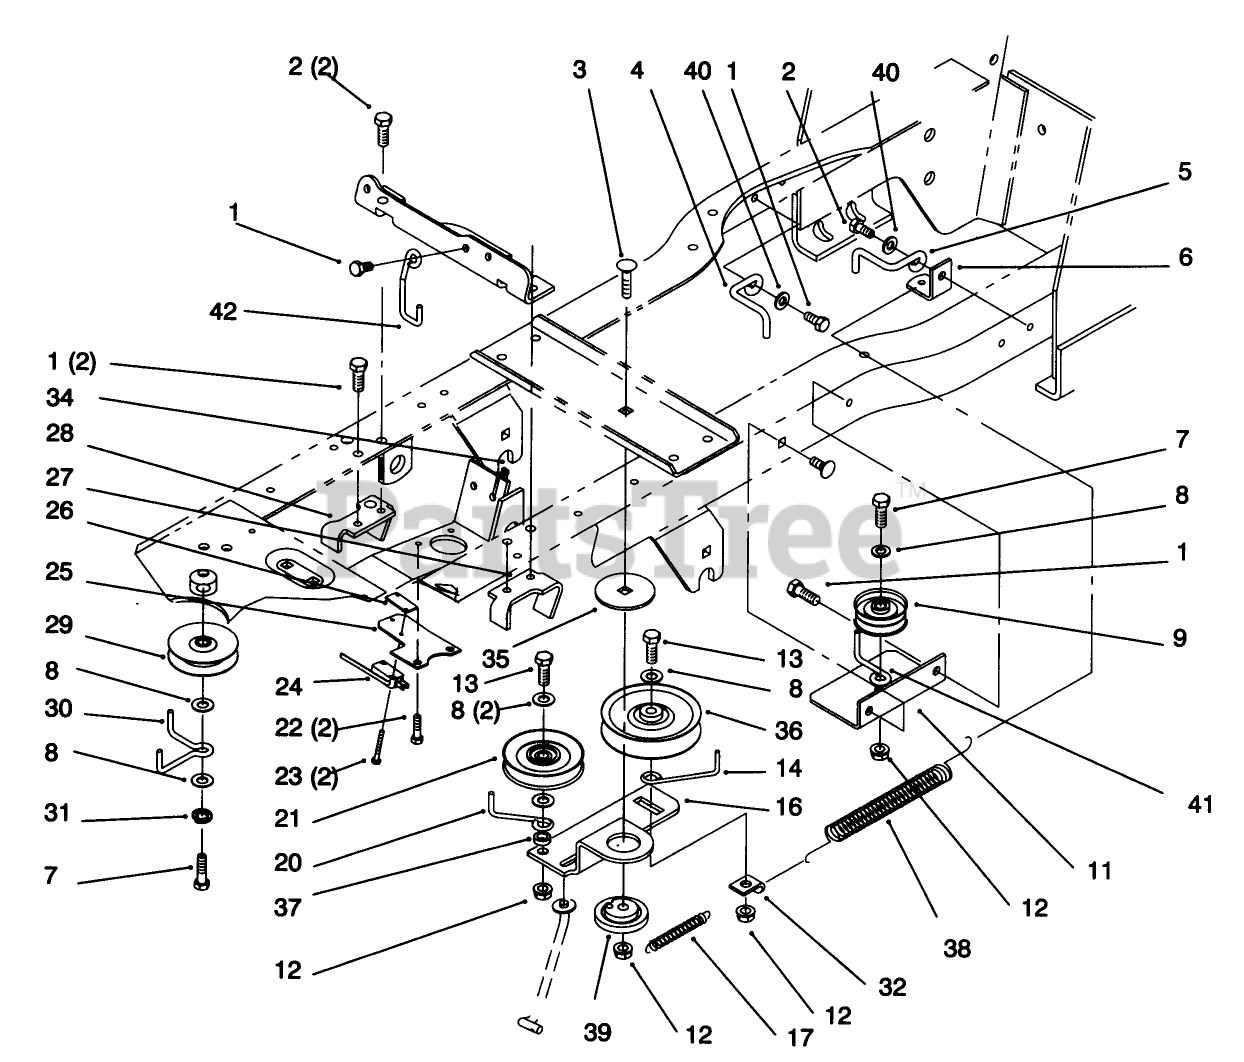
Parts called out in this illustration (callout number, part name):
1	SCREW-TAPTITE
2	SCREW-HWHTF
3	BOLT-CARR
7	SCREW-HH
8	WASHER-FLAT
9	PULLEY IDLER NHI
11	BRACKET-REAR IDLER
12	NUT-LOCK, NI
13	SCREW-HH
14	GUIDE-BELT
16	ARM-IDLER
17	SPRING-EXTENSION
20	GUIDE-BELT
21	PULLEY-IDLER
22	SCREW-HWH
24	SWITCH-MICRO
25	BRKT-MICROSWITCH GEAR
26	NUT-SPEED
27	CLUTCH PEDAL STOP
28	BRAKE BRACKET PLATED
29	PULLEY-IDLER
30	GUIDE-BELT
31	WASHER-LOCK
32	CLIP - SPRING
34	TIE-CABLE
35	WASHER-BEARING
36	PULLEY-IDLER, FLAT
37	SPACER
38	SPRING - CLUTCH
39	BUSHING
40	WASHER-PLAIN
41	GUIDE-BELT
